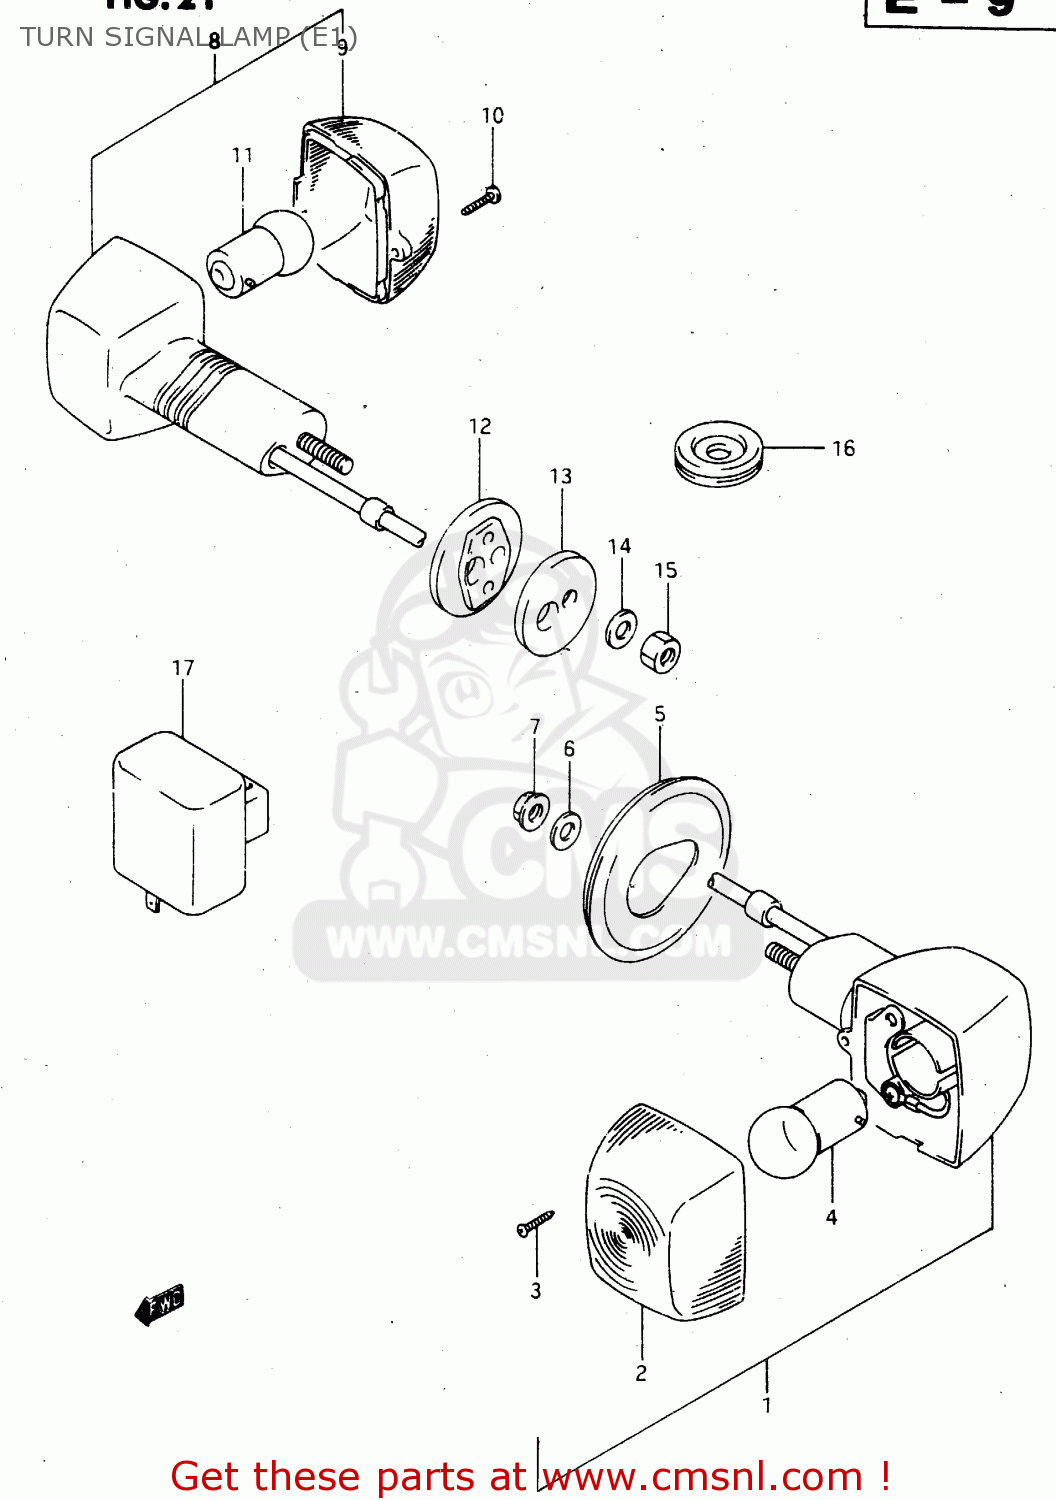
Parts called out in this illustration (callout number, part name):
1	LAMP ASSY, FRONT TURN RH
2	LENS
3	SCREW
4	BULB(12V15W)
5	GROMMET,TURNSIGNAL LAMP
6	WASHER (6.2X14X2)
7	NUT
8	LAMP ASSY,RR TURNSIGNAL,R
9	LENS
10	SCREW
11	BULB(12V15W)
12	SPACER,RR TURN
13	SPACER,RR TURNSIGNAL
14	WASHER
15	NUT 6MM
16	GROMMET
17	RELAY ASSY,TURNSIGNAL
